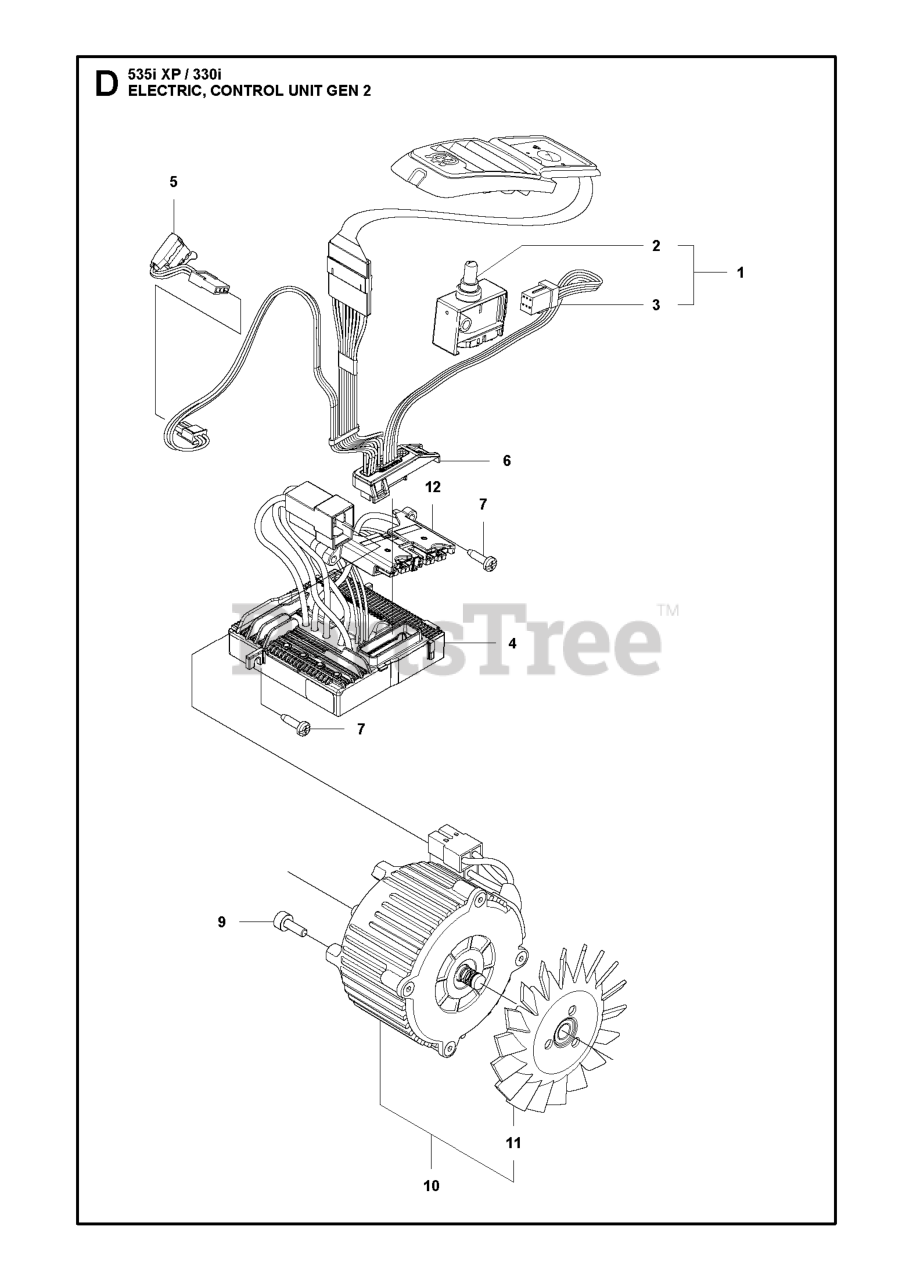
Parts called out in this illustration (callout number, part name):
1	SWITCH KIT BATTERY REAR HANDLE
2	TRIGGER SWITCH IPX4
3	WIRING ASSY SIGNAL REARHANDLE
4	CONTROL UNIT
5	WIRING ASSY
10	MOTOR ASSY BLDC D70
12	CONNECTOR BATTERY
